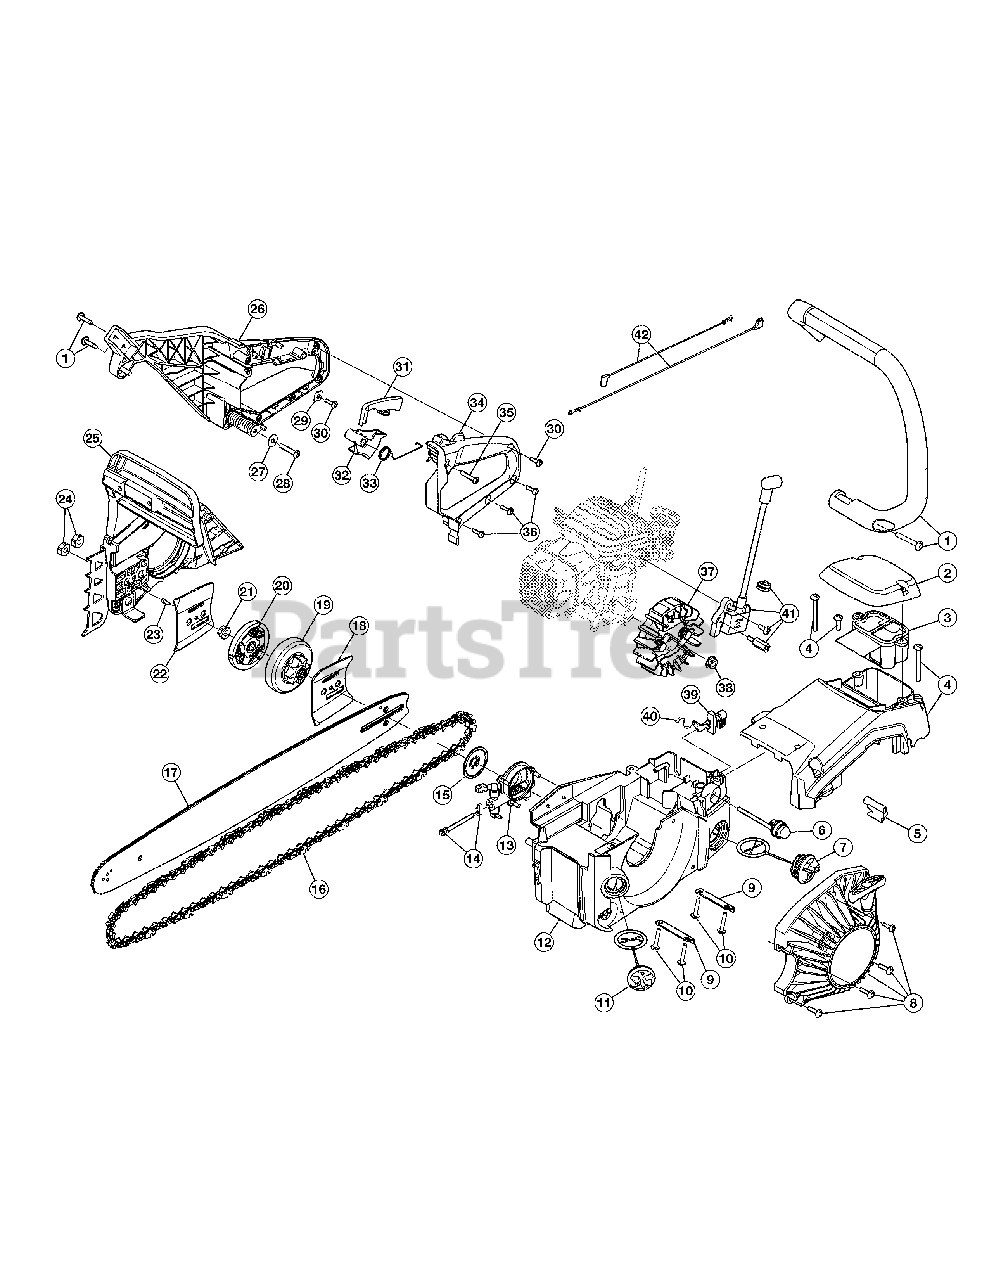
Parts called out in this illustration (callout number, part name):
1	Handle Assembly (with Screws)
2	Air Cleaner Cover Assembly
3	Air Cleaner Assembly
4	Top Cover Assembly
6	Primer Bulb Assembly
7	Fuel Cap
8	Starter Housing Assembly
9	Engine Mount Plate Assembly (Incl. 10)
10	Engine Mount Screw
11	Oil Cap
12	Housing Assembly (Incl. 6, 7 & 11)
13	Oil Pump Assembly
14	Tension Screw & Nut Assembly
15	Oil Pump Shield
16	20" Chain
17	Chain Guide Bar
18	Inner Guide Plate
19	Clutch Drum Assembly
20	Clutch
21	Clutch Nut
22	Outer Guide Plate
23	Guide Plate Screw
24	Chain Guide Bar Nut
25	Chain Brake Assembly
26	Rear Handle Assembly
27	Grip Anti-vibration Washer
28	Grip Anti-vibration Screw
29	Throttle Clamp Washer
30	Throttle Clamp Screw
31	Trigger Release
32	Throttle Trigger
33	Trigger Release Spring
34	Rear Handle Cover Assembly (with Switch)
35	Upper Grip Screw
36	Lower Grip Screw
37	Flywheel Assembly
38	Flywheel Nut
39	Choke Lever Assembly
40	Choke Rod
41	Module Assembly
42	Ground Wire
